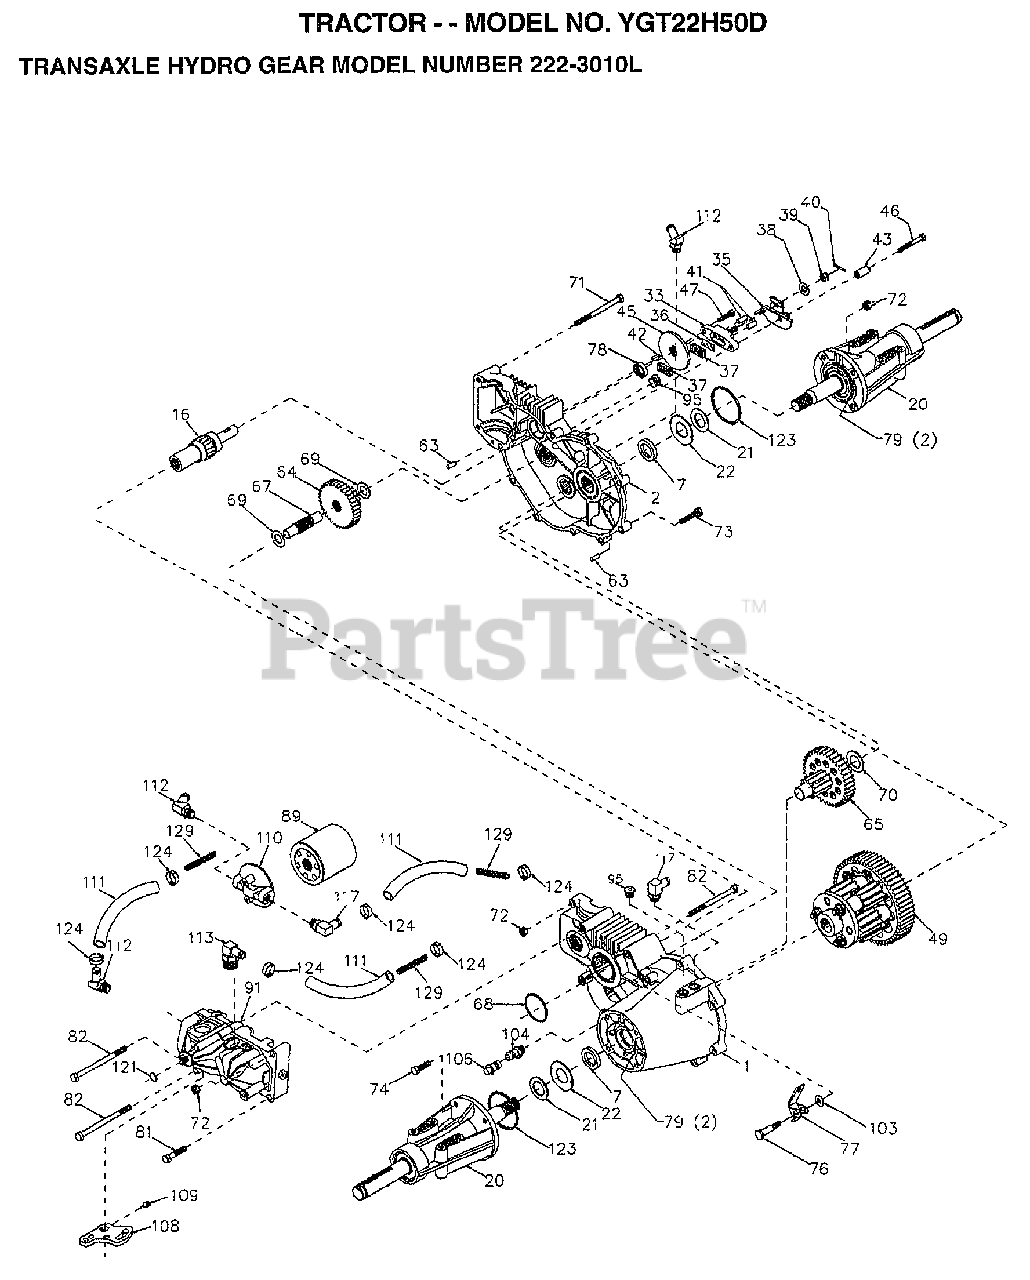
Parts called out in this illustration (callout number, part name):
1	HOUSING LH 70086
2	HOUSING RH 70088
7	SEAL.OIL.44782.HY
16	SHAFT BRAKE 62877
20	AXLE MTG 70087
21	WASHER 44805
22	WASHER 44806
33	YOKE.BRAKE.62589
35	ARM BRAKE 50214
36	PUCK PLATE 44134
37	PUCK BRAKE 44132
38	WASHER HYD 44130
41	PIN BRAKE 44127
42	KEY HI PRO 44143
43	SPACER 50259
45	DISC BRAKE 44090
46	BOLT 1/4-20 44276
47	BOLT 1/4-20 44433
49	DIFFRENTIAL.70251
63	PIN DOWL 44757
64	GEAR.14-38.44776
65	PINION DRIV 70051
67	SHAFT-44779
68	O RING 44781
69	WASHER 44795
70	WASHER 44794
71	BOLT 5/16 44827
72	LOCKNUT.43064
73	BOLT 5/16 44841
74	SCREW 5/16 45089
76	BOLT SHOULD 44785
77	ARM FREEWHL 44786
78	SEAL.OIL.44761
81	BOLT 5/16 43084
82	BOLT 5/16 44820
89	FILTER SPIN 50037
91	PUMP.BDU-10L-122
95	PLUG.9005110-5600
96	FITTING.SAE.50257
103	WASHER.50169
104	CAP.VENT.70109
106	O-RING.ASM.70110
108	ARM.CONTROL.45007
109	SCREW.SET.50018.
110	FILTER.HEAD.50207
111	HOSE.50632
112	FITTING.SAE.50604
113	FITTING.SAE.50592
117	FITTING.SAE.50589
123	O-RING.50405
124	CLAMP.50590
129	SPRING.LONG.50667
